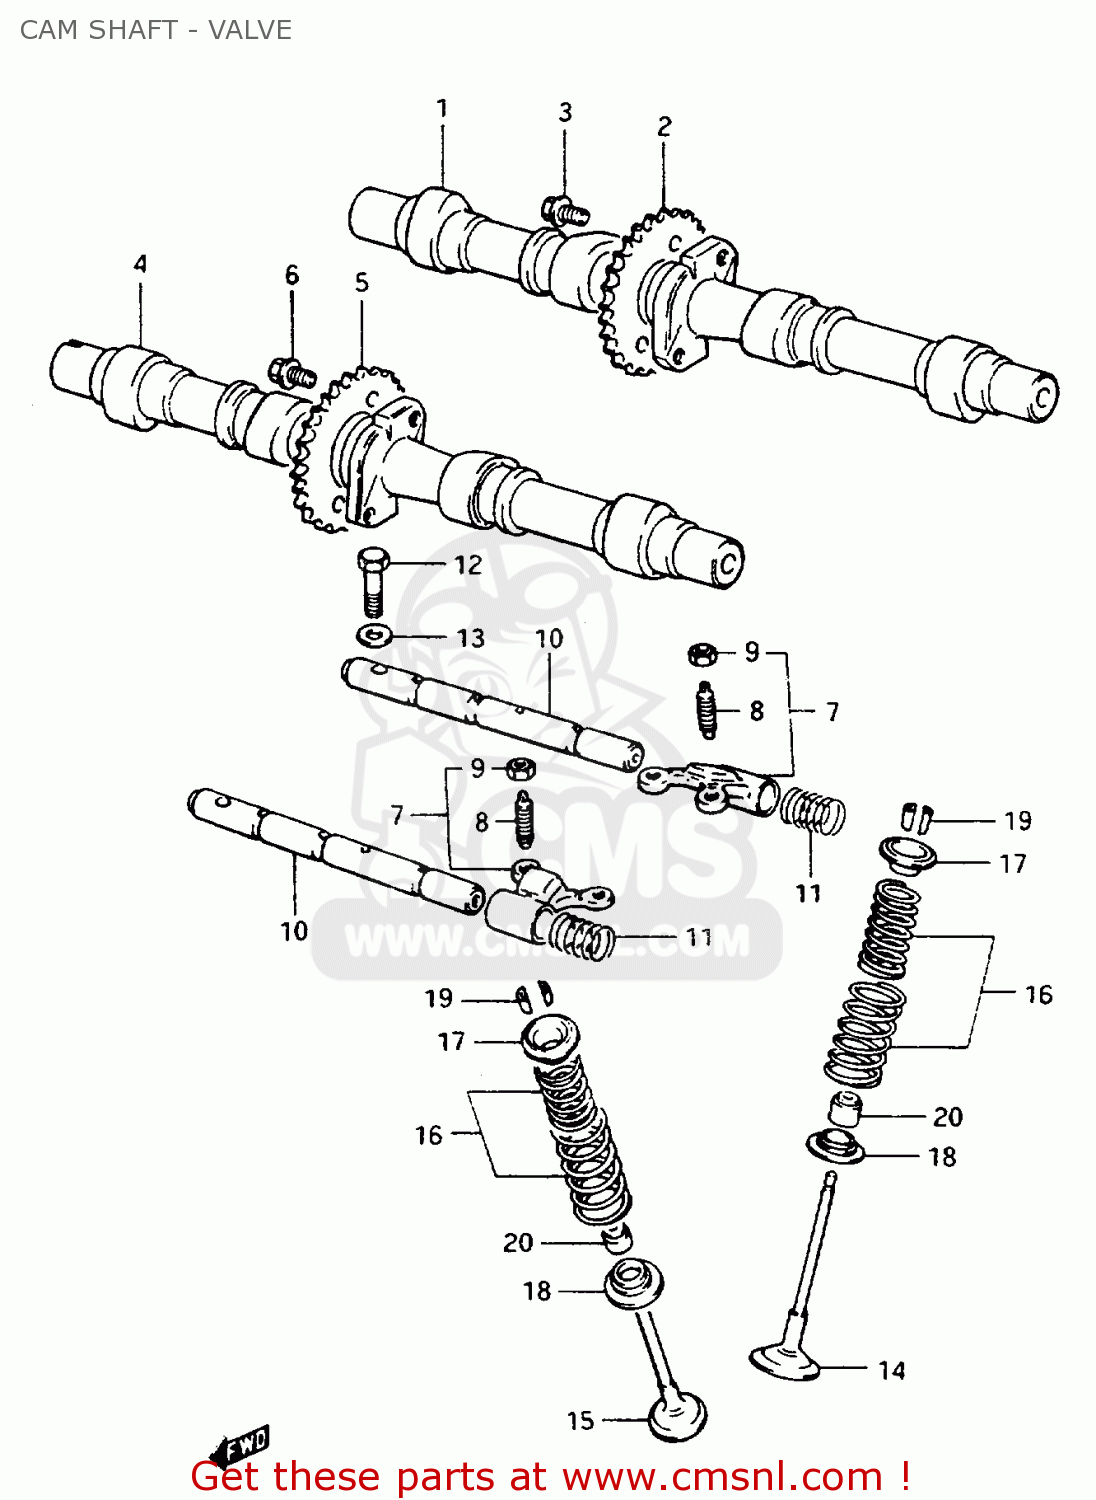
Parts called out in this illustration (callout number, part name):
1	CAMSHAFT,INTAKE
2	SPROCKET,INTAKE CAMSHAFT
3	BOLT(7X11)
4	CAMSHAFT,EXHAUST
5	SPROCKET,INTAKE CAMSHAFT
6	BOLT(7X11)
7	ARM,VALVE ROCKER
8	SCREW,TAPPET ADJUSTING
9	NUT,ADJUSTING
10	SHAFT,VALVE ROCKER
11	SPRING
12	BOLT
13	WASHER, LOWER
14	VALVE,INTAKE
15	VALVE,EXHAUST
16	SPRING SET,VALVE
17	RETAINER,VALVE SPRING
18	SEAT,VALVE SPRING
19	COTTER VALVE
20	OIL SEAL
